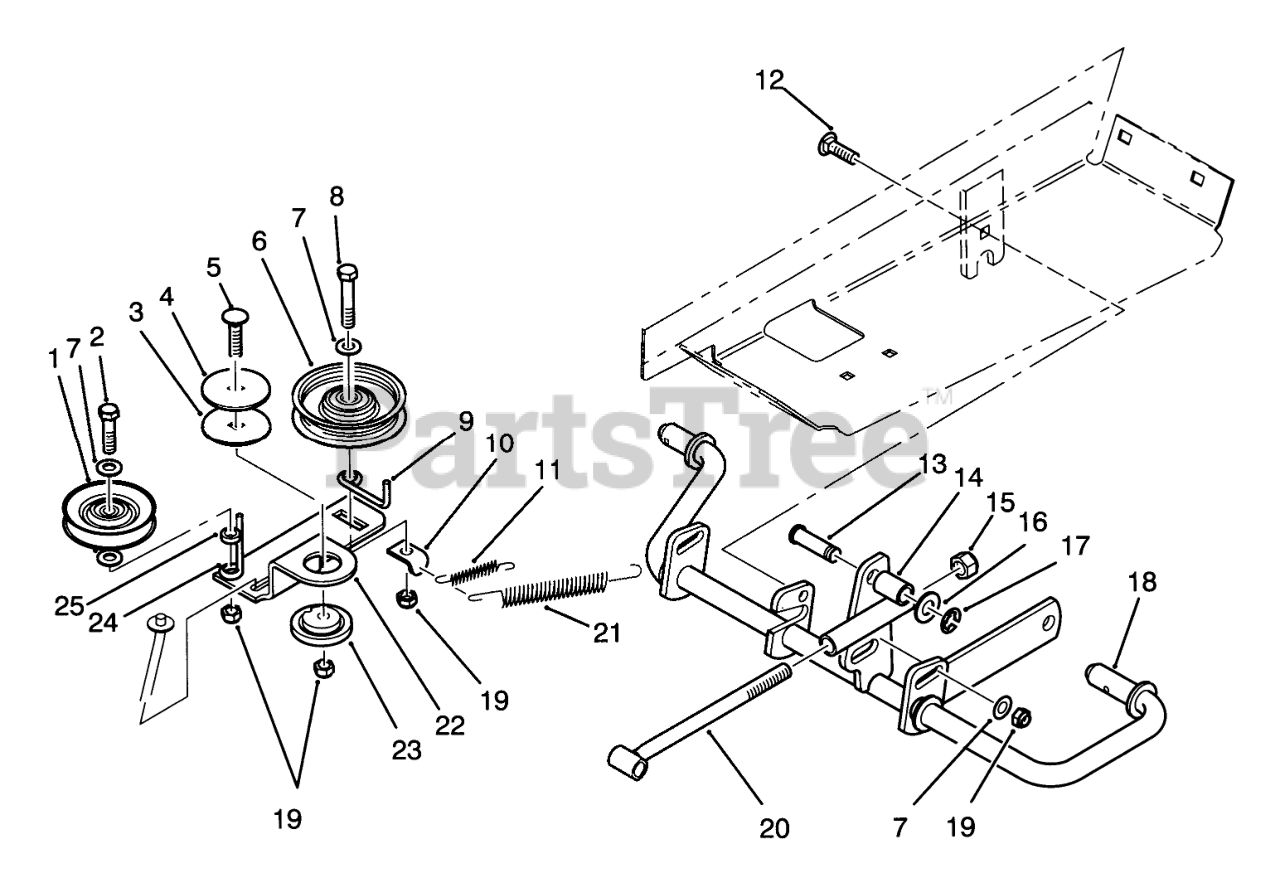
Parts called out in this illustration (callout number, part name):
1	Pulley
2	SCREW-HH
3	WASHER-BEARING
4	WASHER
5	SCREW-CARR
6	Idler Pulley
7	WASHER-FLAT
8	SCREW-HH
9	GUIDE-BELT
10	CLIP - SPRING
11	SPRING-EXTENSION
12	BOLT-CARR
15	NUT-LOCK, NI
16	WASHER-FLAT
17	RING-RETAINING, EXTERNAL
18	Shaft
19	NUT-LOCK, NI
21	SPRING - CLUTCH
22	ARM-IDLER
23	BUSHING
24	GUIDE-BELT
25	SPACER
